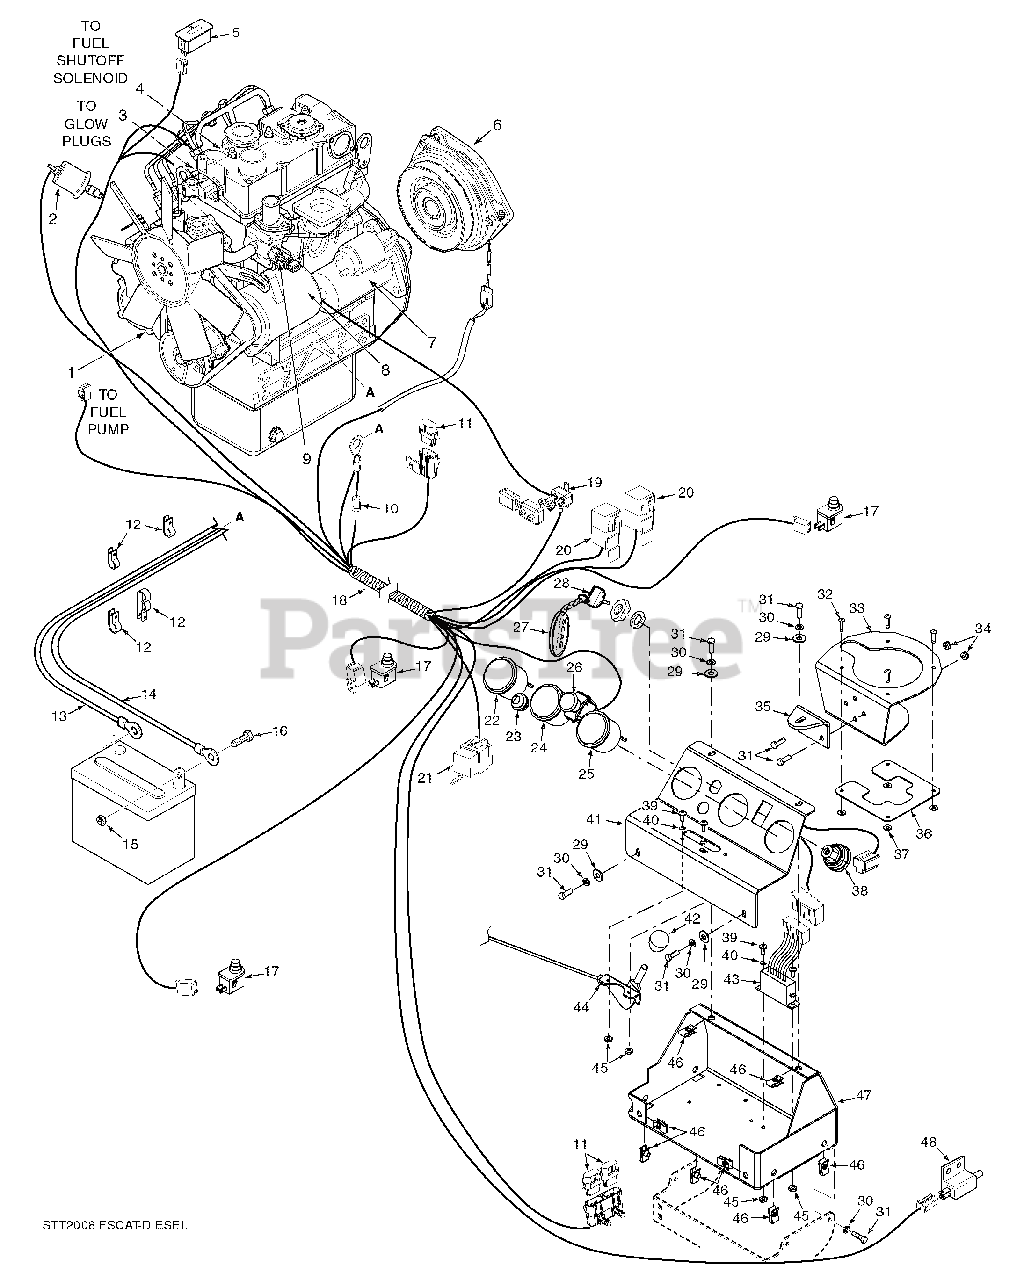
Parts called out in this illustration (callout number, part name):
1	Fuel Pump
2	Oil Pressure Sender
3	Glow Plugs
4	Fuel Shutoff Solenoid
5	Hourmeter
6	Clutch, Ogura GT 3.5 - 1.125 Bore
7	Starting Motor
8	Alternator
9	Sending Unit, Water Temp.
10	Diode
11	Fuse, 20 AMP
12	Clamp, Cable 1/2” ID.
13	Cable, Battery - Red
14	Cable, Battery - Black
15	Nut, Hex 1/4-20
16	Bolt, Hex Head 1/4-20 x .5”
17	Switch, Interlock, Normally Open
18	Main Wire Harness, STT Cat
19	Circuit Breaker, 50 AMP
20	Relay, 12V 40 AMP Hi Capacity
21	Relay, 12V 40 AMP Standard
22	Volt Meter
23	Indicator Light, Glow Plugs
24	Engine Oil Pressure Gauge
25	Water Temperature Gauge
26	Switch, PTO
27	Key Assembly w/Fob
28	Key, Ignition
29	Flat Washser, 1/4”
30	Lockwasher, 1/4”
31	Bolt, Hex Head 1/4-20 x 3/4”
32	Pop Rivet, 3/16” x 5/8”
33	Cupholder
34	Nut, Elastic Stop 1/4”-20
35	Bracket, Cupholder Mounting
36	Retainer, Cupholder
37	Flatwasher, 0.196 ID.
38	Key Switch
39	Screw, Phillips Washer Head #10-32 x 1/2”
40	Lockwasher, #10 External Tooth
41	Instrument Panel, Top w/Decals
42	Knob, Throttle
43	Electronic Control Module
44	Throttle Control
45	Nut, Hex #10-32
46	U-Nut, 1/4-20
47	Base, Instrument Panel
48	Switch, Interlock, Park Brake Normally Open
